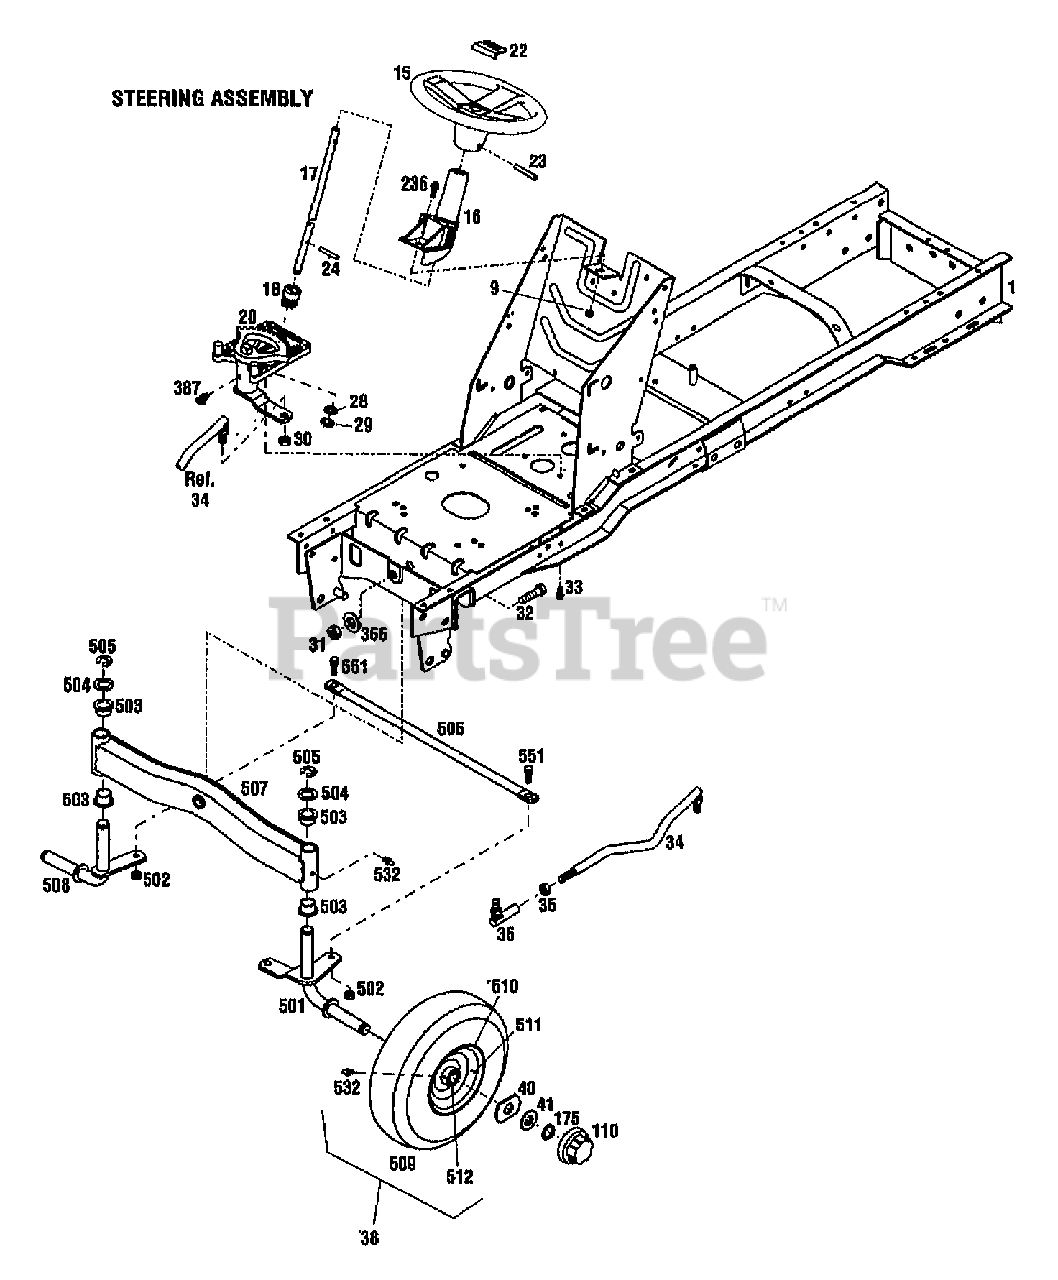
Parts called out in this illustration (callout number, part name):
1	ASSM-FRAME LTX
9	NUT-HFLK 5/16-18 ZP
15	WHEEL-STEERING
16	SUPPORT-STEERING SHAFT
17	SHAFT-STEERING
18	GEAR-PINION
20	ASSM-STEERING GEAR
22	CAP-STEERING
23	PIN-ROLL .25X2.25
24	PIN-ROLL 1/4 X 1-1/4
28	WASHER-1.0X.64X.09
29	RING-RETAINING
30	NUT-HEX/JAM 1/2-20
31	NUT-H/LK 5/8-11
32	SCR-HH
33	SCR-HFLK 5/16-18X.75
34	LINK-DRAG
35	NUT-JAM
36	JOINT-BALL
38	ASSM-WHEEL & TIRE FRONT
40	WASHER-SPEC .75X2.50
41	WASHER-1.38 X.765X .06 ZP
110	CAP-HUB
175	RING-RET."E".577 ID
236	SCR-HFLK 5/16-18X.75 ZP
366	WASHER-1.75X.687X.134 ZP
387	FITTING-GREASE 90 DEGREE
501	ASSM-SPINDLE LH
502	NUT-LOCK
504	WASHER-1.25X.765X.049
505	RING-HEAVY EXT HD 1.0 ID
508	ASSM-SPINDLE WHEEL RH
509	TIRE 15X6.00-6RS
510	DISC WHEEL
511	STEM-VALVE
512	BEARING-BALL W/SEAL
532	FITTING-GREASE 1/4-28X2.00
551	SCR-SHOULDER
